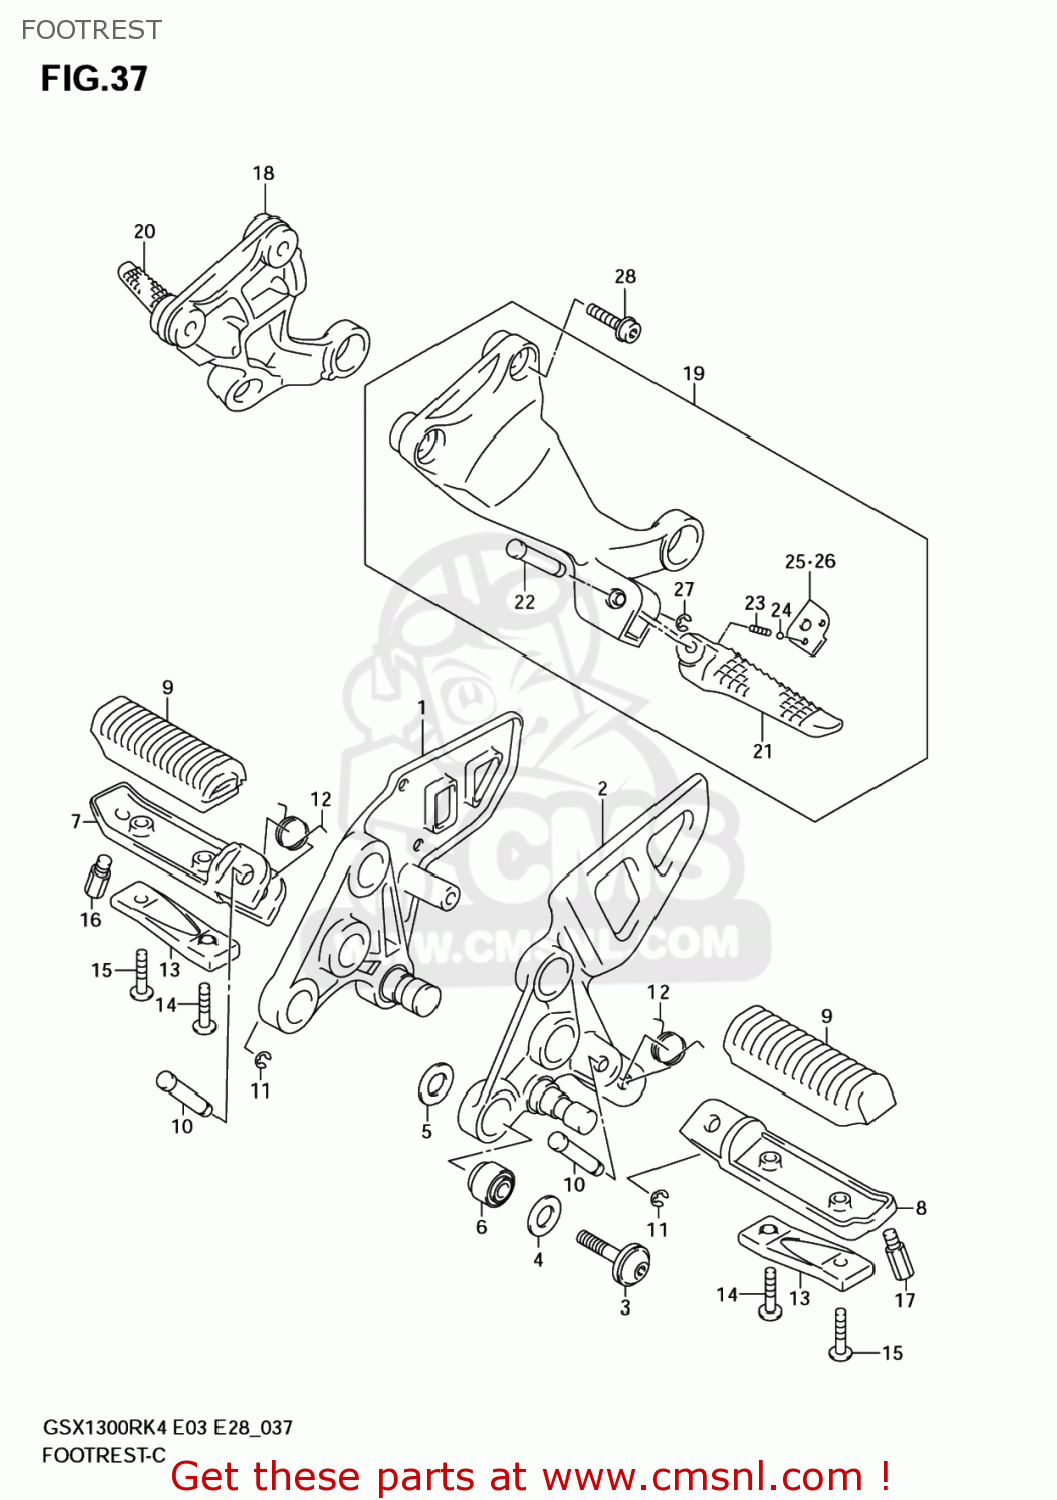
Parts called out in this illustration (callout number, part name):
1	BRACKET,FR FOOTREST,R
2	BRACKET,FR FOOTREST,L
3	BOLT(8X30)
4	WASHER(13.7X24X2)
5	WASHER(17.2X24X2.2)
6	BUSH(8.4X20X16)
7	BAR,FR FOOTREST,R
8	BAR,FR FOOTREST,L
9	RUBBER,FOOTREST BAR
10	PIN
11	E.RING
12	SPRING
13	BALANCER,FR FOOTREST LWR
14	SCREW
15	SCREW
16	BOLT,BANK SENSOR
17	BOLT,BANK SENSOR
18	FOOTREST ASSY,PILLION,R
19	FOOTREST ASSY,PILLION,L
20	BAR,PILLION FOOTREST,R
21	BAR,PILLION FOOTREST,L
22	PIN
23	SPRING
24	BALL
25	PLATE,PILLION FOOT,R
26	PLATE,PILLION FOOT,L
27	E-RING
28	BOLT(8X30)
